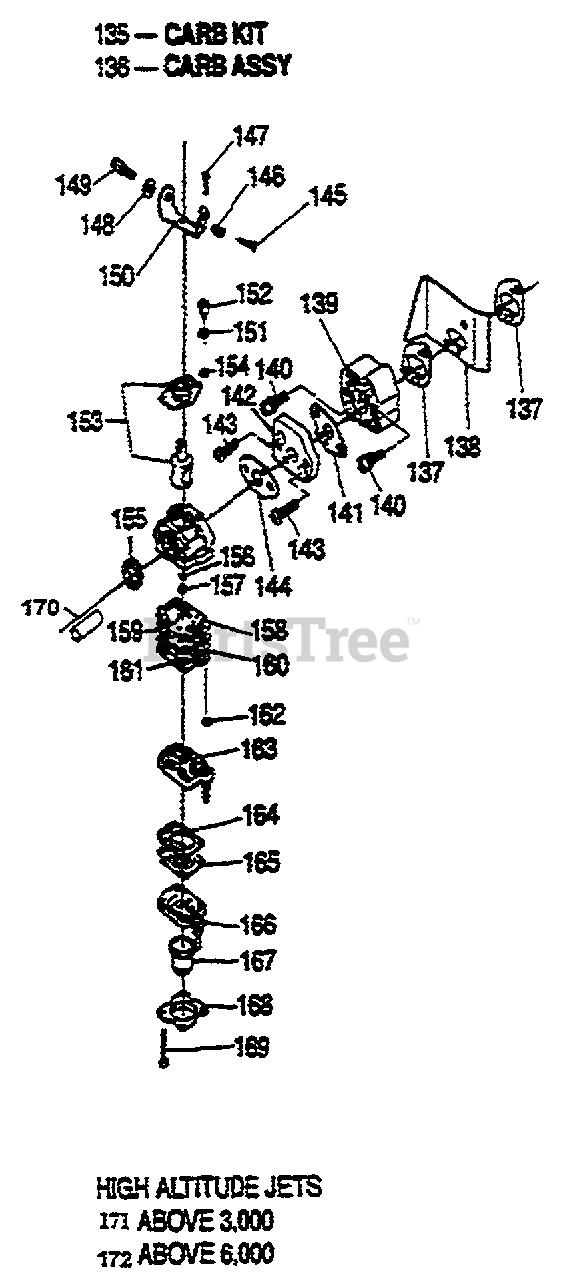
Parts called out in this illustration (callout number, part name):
135	CARB. KIT
136	CARB ASSY
137	GASKET, INSULATOR
139	INSULATOR
140	SCREW & WASHER
141	GASKET, CARB.
144	GASKET, CARB.
145	SCREW, IDLE
146	SPRING, IDLE
148	NUT, CABLE ADJ.
149	ADJUSTER, CABLE
153	VALVE, THROTTLE
154	RING, SWIVEL
158	GASKET, PUMP
159	DIAPHRAGM
162	SCREEN, INLET
163	BODY ASSY
164	GASKET DIAPHRAGM
165	DIAPHRAGM
166	BODY PRIMER PUMP
167	PRIMER PUMP
168	PRIMER PUMP COVER
169	COVER SCREW
171	HIGH ALTITUDE JET
172	HIGH ALTITUDE JET
